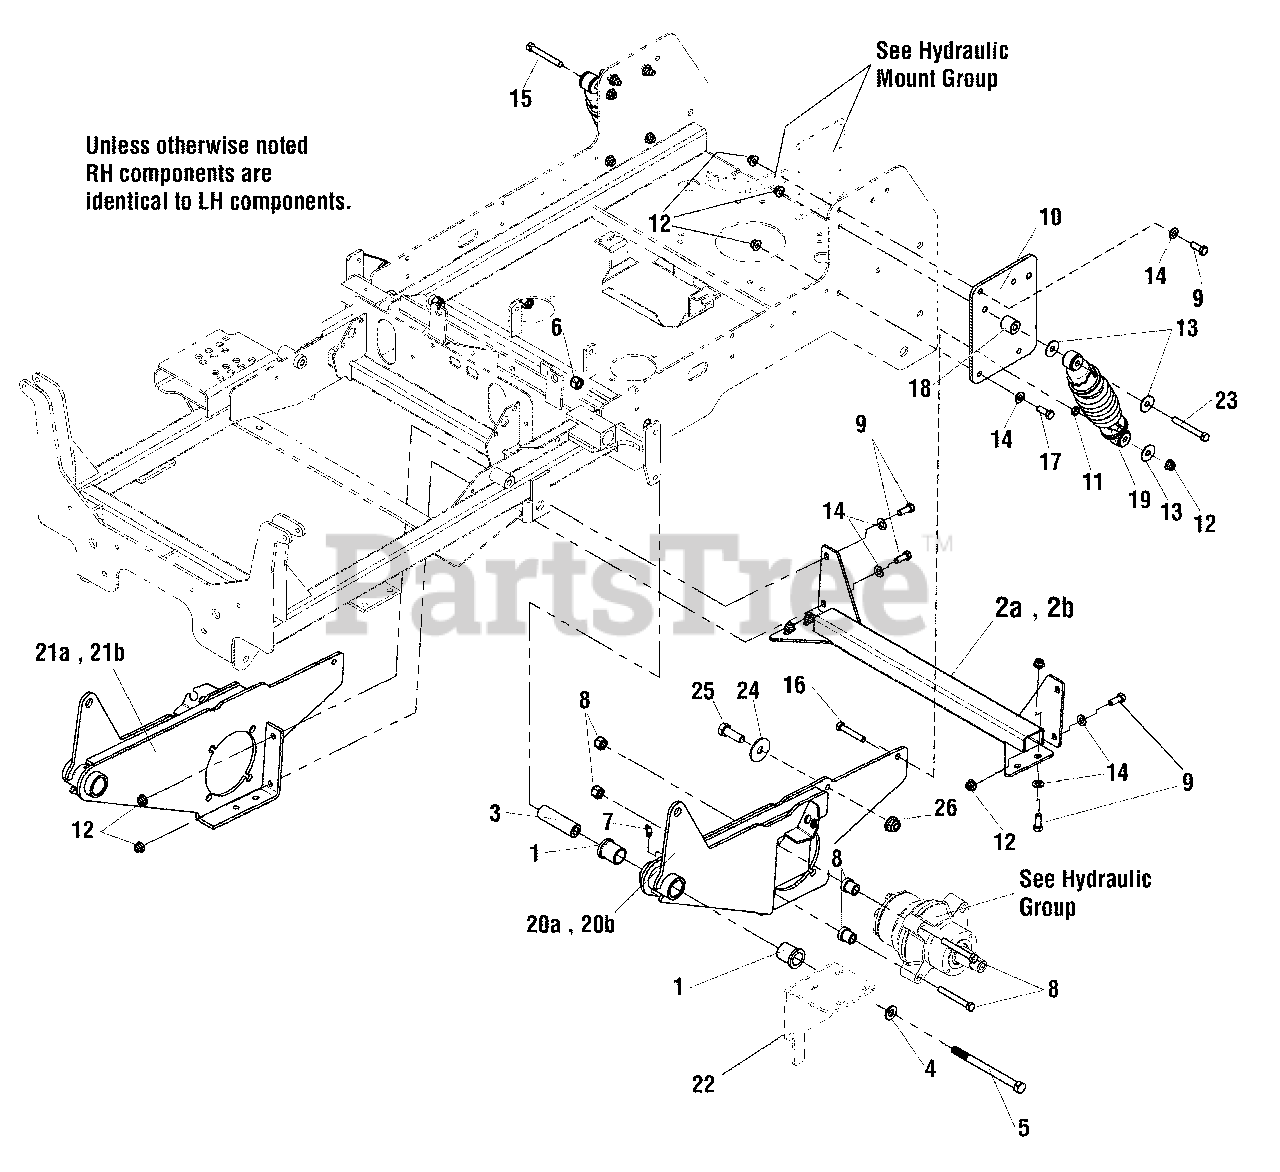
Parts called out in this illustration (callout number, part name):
1	BUSHING, FLANGE
3	SPACER, .52 X 1.00 X 3.42
4	WASHER, 1/2 GD9 YZ
5	BOLT, 1/2-13 X 6-1/2 GD8 YZ
6	NUT, 1/2-13 HEX NYLON LOCK
7	GREASE FITTING, 1/4-28 STRAIGHT
9	BOLT, 3/8-16 X 1-1/4 GD5
10	PLATE, FRAME SUPPORT - ORG
11	SPACER, .39 X 1.00 X .50
12	NUT, 3/8-16 HEX NYLOCK FLANGE
13	WASHER, 3/8 FENDER
14	WASHER, 3/8 GD.9 FLAT
15	BOLT, 3/8-16 X 3-1/2 GD5 YZ
16	BOLT, 3/8-16 X 2-1/4 GD5 TFL
17	BOLT, 3/8-16 X 1 GD5 YZ
18	SPACER, .39 X 1.00 X 1.25, CZ
19	SHOCK ABSORBER, # 7417-106
22	FUEL TANK MOUNT (SEE FUEL TANK & MOUNT GROUP)
23	BOLT, 3/8-16 X 3-1/2 GD5 YZ
24	SPACER, .34 X 1.54 X .25 UHMW
25	SCREW, 5/16-18 X 1, PHILLIPS HD, BZ
26	NUT, 5/16-18 Hex Nylock Flange
